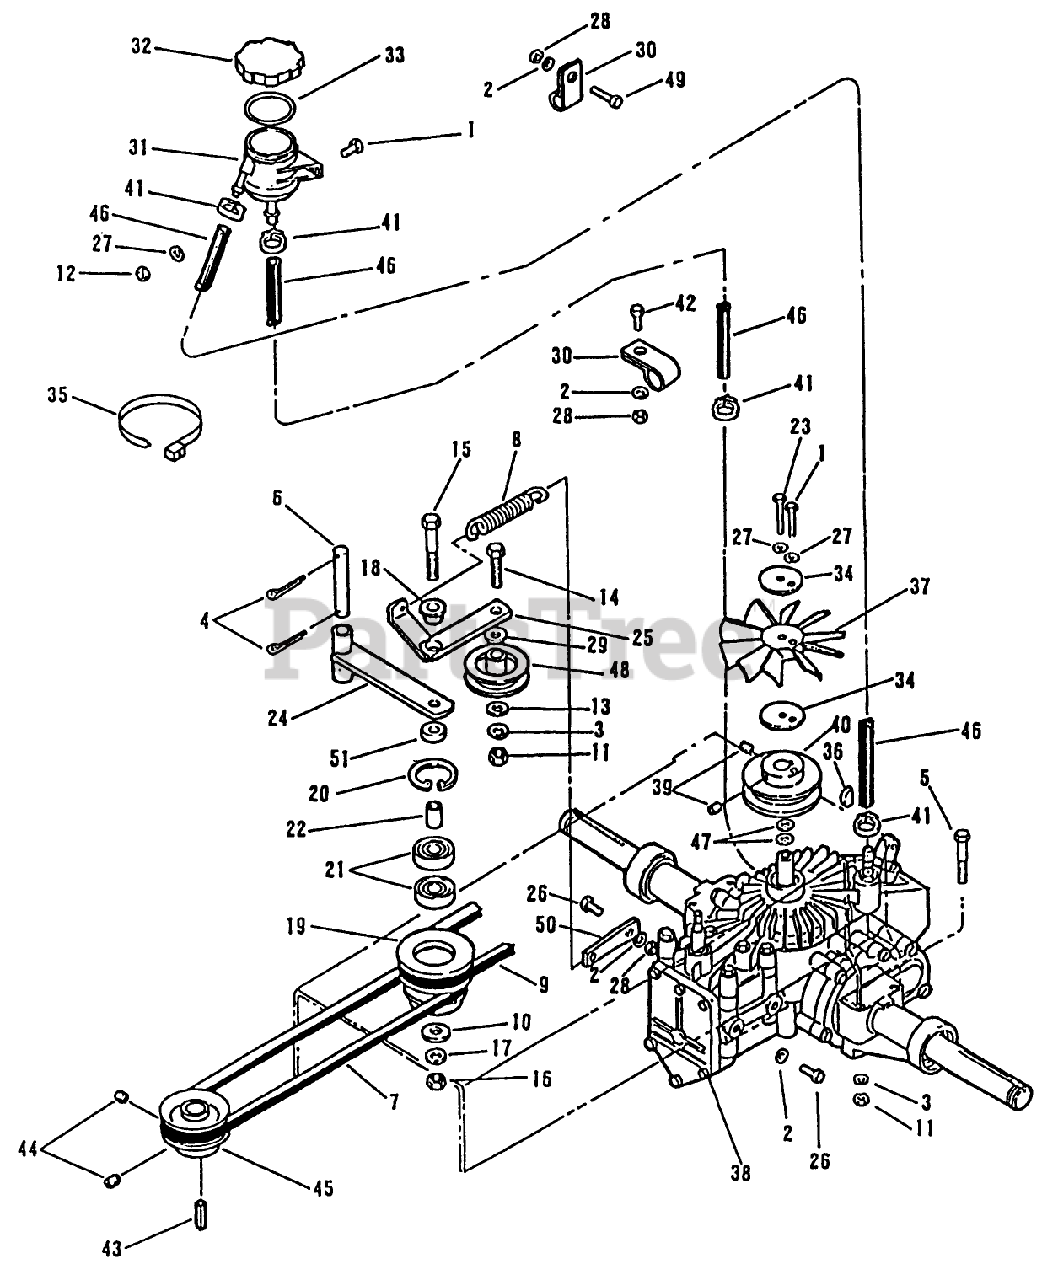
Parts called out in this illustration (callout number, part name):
19	IDLER ASSEMBLY
24	IDLER ARM WELDMT *B
26	SCREW - HEX
33	GASKET,COVER
34	FRAME MTG WASHER LB
41	CLAMP, SNAP
44	SET SCREW
46	HOSE-HYDRAULIC
